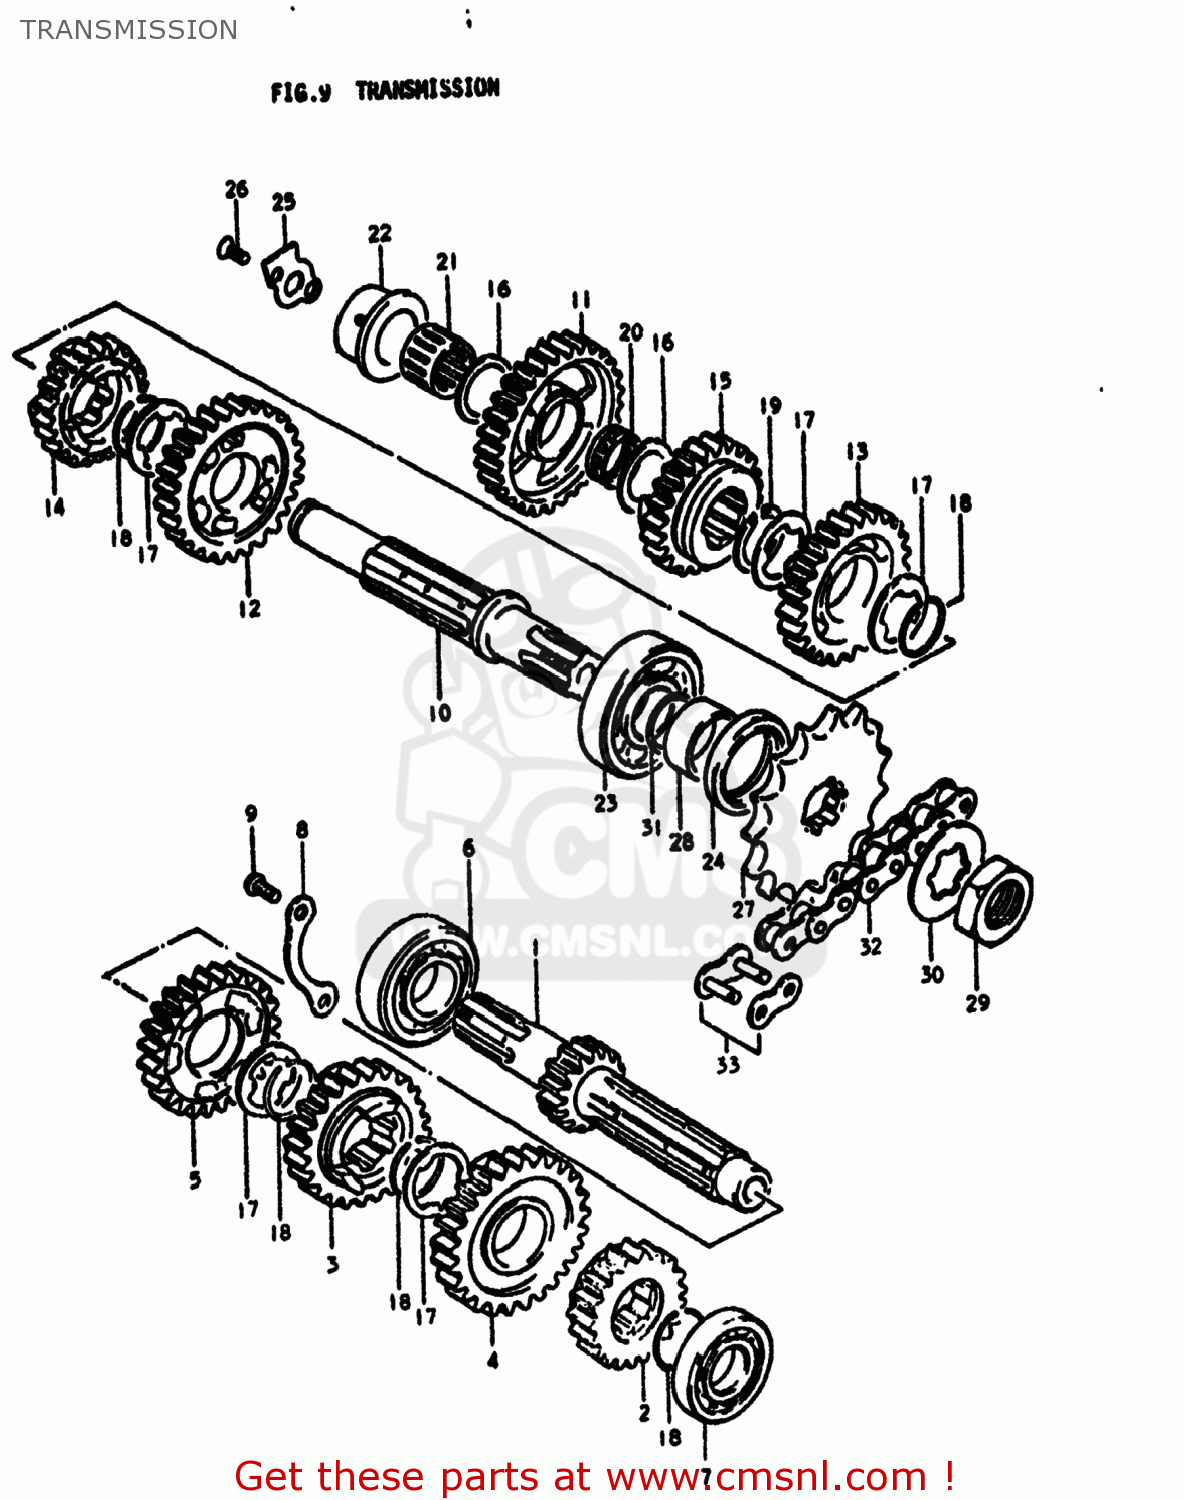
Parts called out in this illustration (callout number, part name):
1	SHAFT,COUNTER
2	GEAR,SECOND DRIVE
3	GEAR,THIRD DRIVE
4	GEAR,FOURTH DRIVE
5	GEAR,FIFTH DRIVE
6	BEARING
7	BEARING, LH
8	PLATE,COUNTERSHAFT BEARING
9	SCREW 6X12
10	SHAFT,DRIVE
11	GEAR,FIRST DRIVEN
12	GEAR,SECOND DRIVEN
13	GEAR,THIRD DRIVEN
14	GEAR,FOURTH DRIVEN
15	GEAR,FIFTH DRIVEN
16	WASHER (20X30X1)
17	WASHER,LOCK
18	RING,SNAP
19	CIRCLIP
20	BEARING(20X24X10).8
21	BEARING(20X24X16.8)
22	BUSHING
23	BEARING
24	SEAL,OIL(32X42X6)
25	PLATE,DRIVESHAFT BEARING
26	SCREW
27	SPROCKET,ENGINE
28	SPACER(22X32X11.5)
29	NUT
30	WASHER,LOCK
31	O RING(D:1.7,ID:22)
32	CHAIN ASSEMBLY,DRIVE
33	JOINT ASSEMBLY,CHAIN
